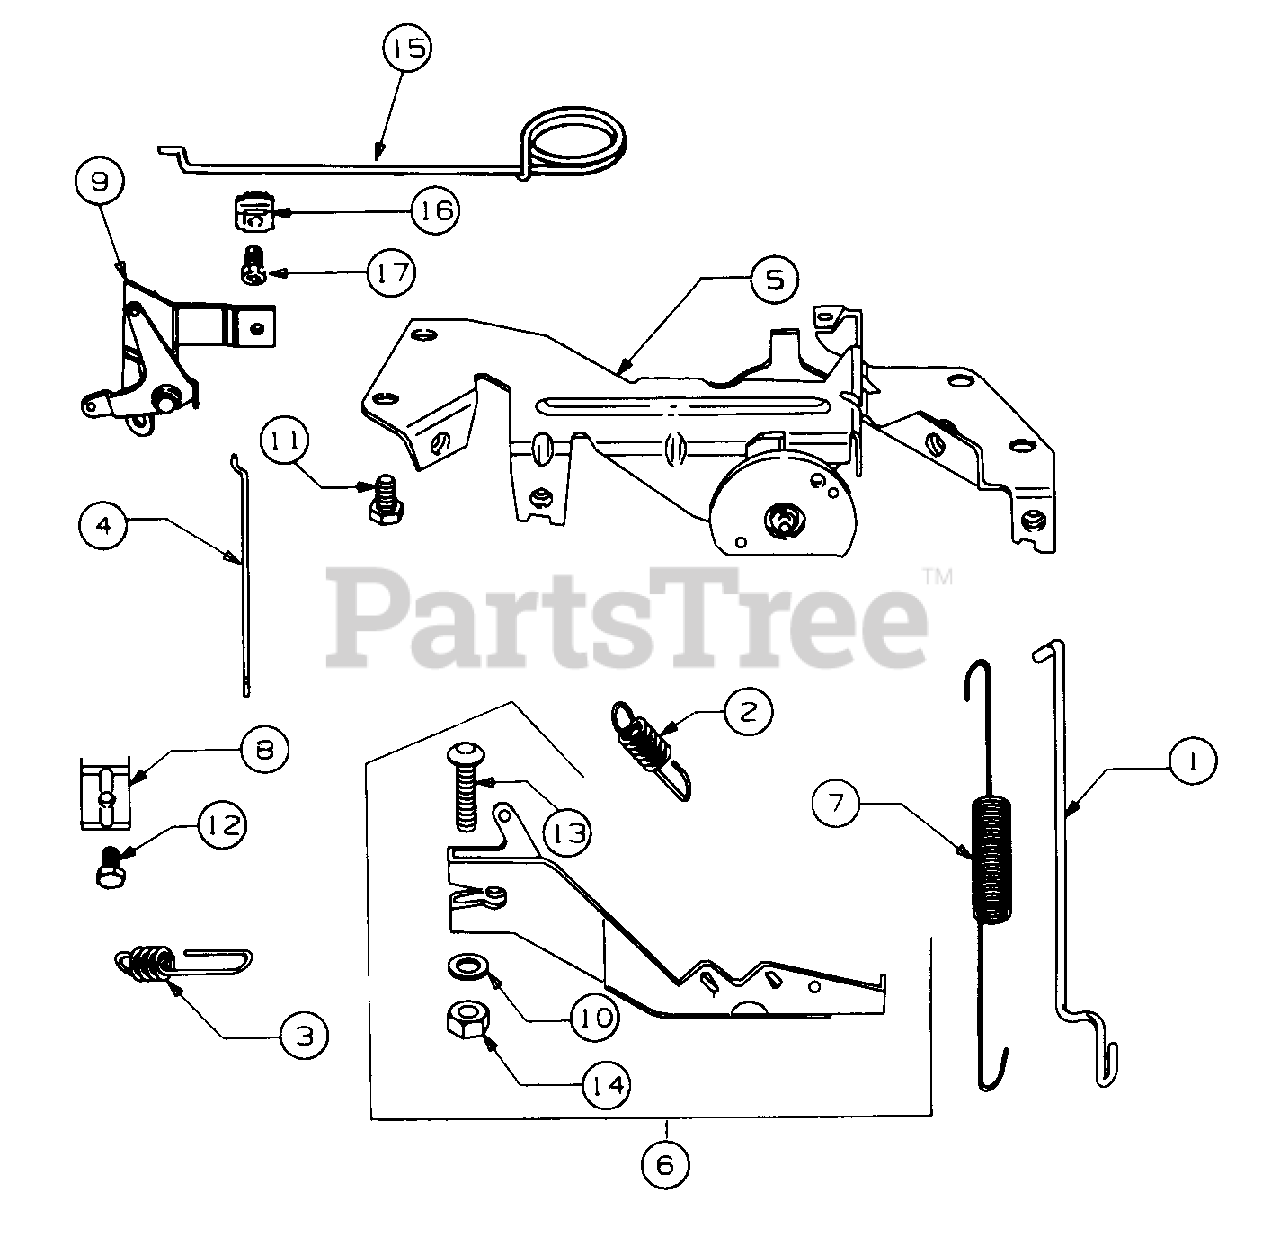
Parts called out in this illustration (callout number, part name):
1	Link, Governor
2	Spring, Governor
3	Spring, Governed Idle
4	Link, Choke
5	Bracket, Governor Control
6	Lever Assy, Governor
7	Spring, Governor Link
8	Clamp, Casing
9	Bracket, Choke Control
11	Screw, Sem
12	Screw, Hex Head
14	Nut, Hex
15	Rod, Manual Choke
16	Clip, Friction
17	Screw, Sem
